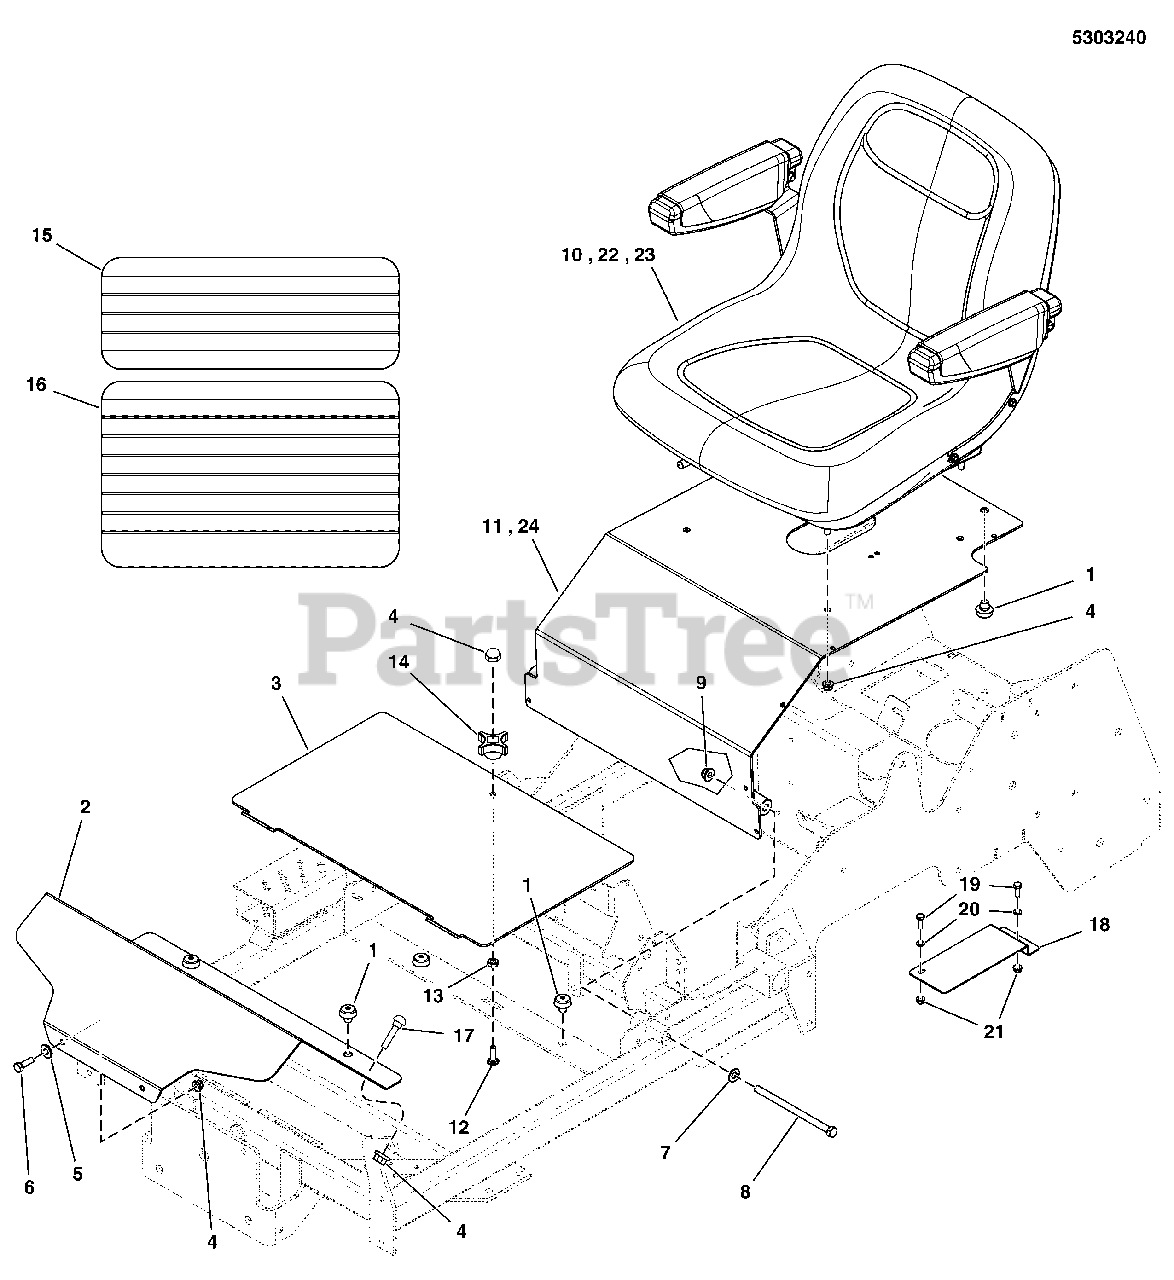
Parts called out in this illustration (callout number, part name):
1	MNT, VBRTN, RBBR
2	PLATE, FLOOR, RIDGID, IS700 - ORG
3	PLATE, FLOOR, REMOVABLE, IS700 - ORG
4	NUT, 5/16-18 HEX NYLOCK FLANGE
5	WASHER, 5/16 SAE
6	BOLT, 5/16-18 X 1 GD5 YZ
7	WASHER, 3/8 SAE
8	BOLT, 3/8-16 X 5-1/2 GD5 YZ
9	NUT, 3/8-16 HEX NYLOCK FLANGE
10	SEAT, XB-180, NO LOGO, BLACK
11	ASSM, SEAT PLATE W/DECALS - CIT XT (5409985C)
12	BOLT, 5/16-18 X 1-1/4, CARRIAGE YZ
13	NUT, 5/16-18,GR8, HEX, CNTR LK, ZINC/CL
14	KNOB-INT THR .312-18 4-ARM 2.12WD 1.06LG
15	SAFETY WALK, FLOOR REST, 6.00 X 16.00
16	SAFETY WALK, FLOOR PLATE, S50X, 10X16
17	BOLT, 5/16-18 X 3/4, CARRIAGE
18	PLATE, SEAT BELT GUARD, IS700 - BLK
19	SCREW, 1/4-20 X 1, ALLEN BH, CZ
20	WASHER, 1/4 SAE (5025154)
21	NUT, 1/4-20 HEX NYLOCK FLANGE (5025391)
22	SEAT, 907 SEAT INC
23	SEAT, 907 WITH ARM RESTS W/SWITCH
24	ASSM, SEAT PLATE W/DECAL (5416034C)
